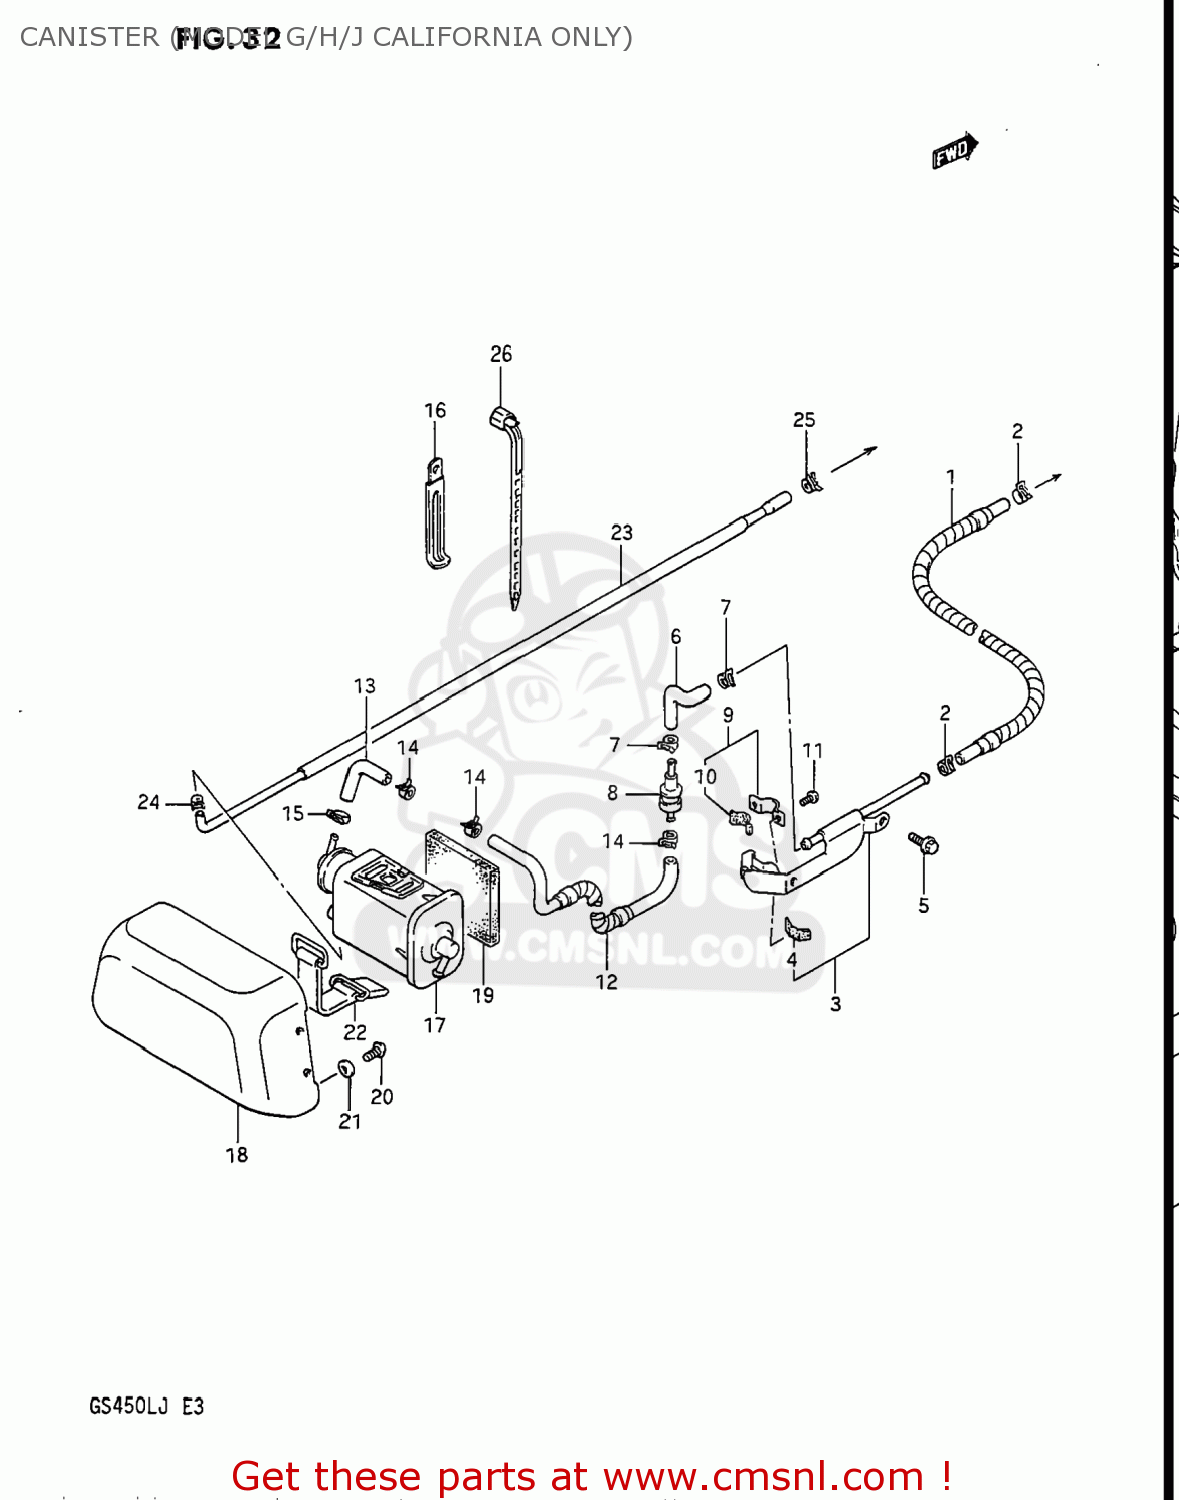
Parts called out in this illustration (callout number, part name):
2	(CA) CLIP
4	CUSHION
5	BOLT
6	HOSE
7	(CA) CLIP
8	VALVE,FUEL TANK BREATHER
9	PLATE,FUEL TANK BREATHER NO.2
10	CUSHION
11	SCREW
12	(CA) HOSE,VALVE-JOINT
13	HOSE
14	(CA) CLIP
15	CLAMP
16	CLAMP
17	CANISTER ASSEMBLY,CHARCOAL
18	(CA) COVER,CANISTER
20	SCREW
21	WASHER
22	BAND
23	HOSE,JOINT
24	CLIP
25	CLAMP(L:165)
